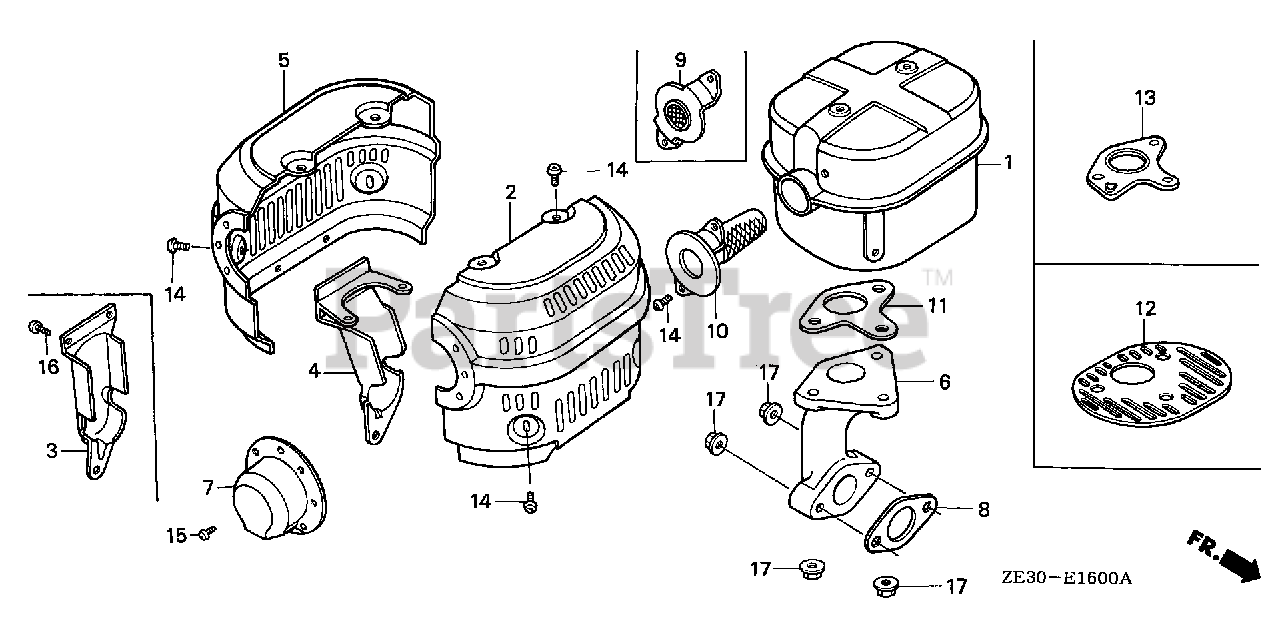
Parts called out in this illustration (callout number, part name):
1	MUFFLER
2	PROTECTOR, R. MUFFLER (ALUMINIZED)
5	PROTECTOR, L. MUFFLER (ALUMINIZED)
6	PIPE, EX.
8	GASKET, EX. PIPE
9	FLANGE, BAFFLE
11	GASKET, MUFFLER
11	GASKET, MUFFLER (NIPPON LEAKLESS)
14	SCREW, TAPPING (5X8)
17	NUT, FLANGE (8MM)
